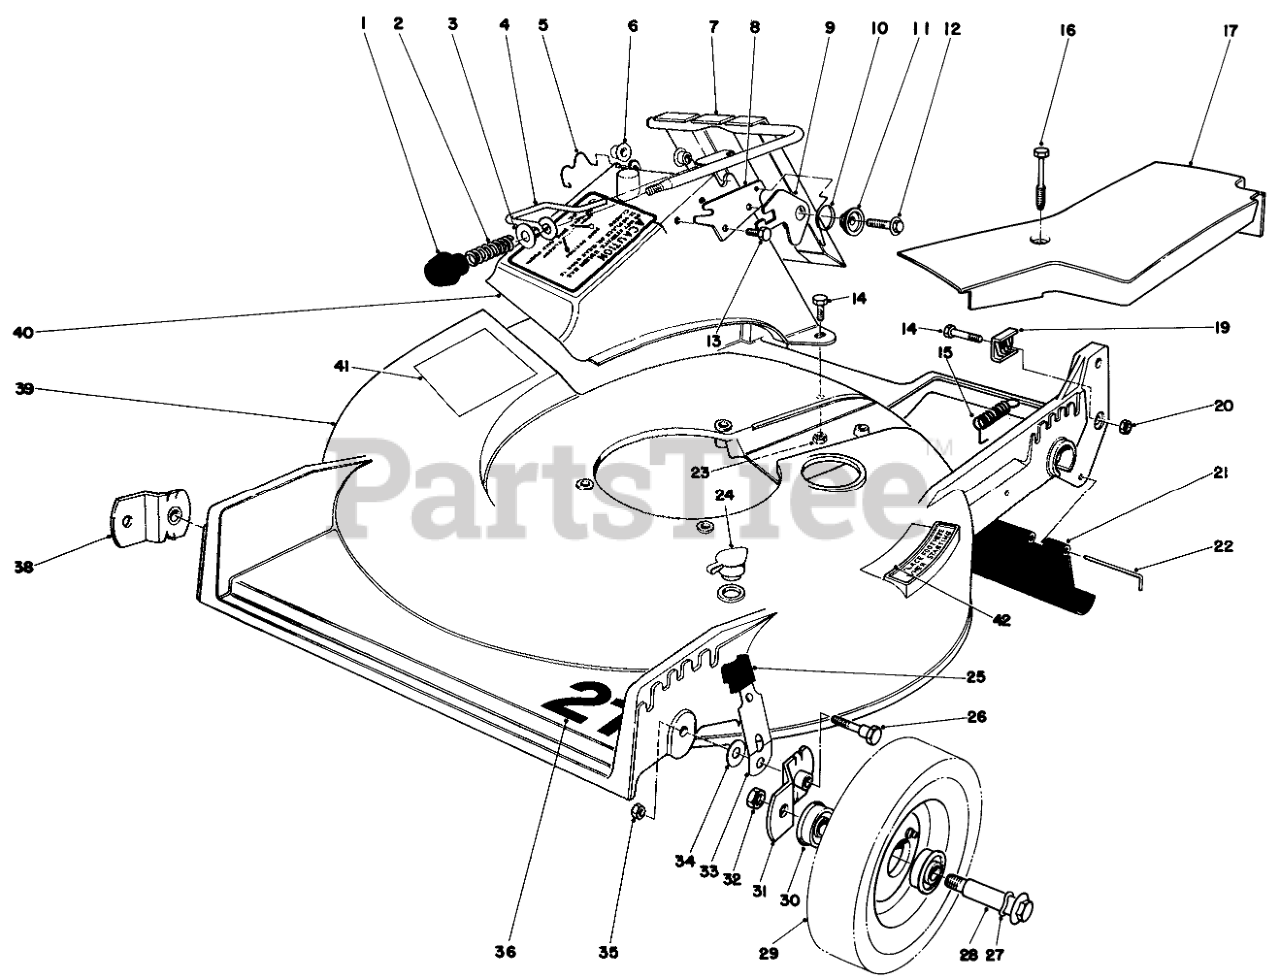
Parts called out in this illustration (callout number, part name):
2	COMPRESSION SPRING
3	WASHER
4	DOOR LATCH
5	Door Retainer
6	BUSHING-NYLON
7	DOOR & HANDLE WA
8	DOOR LATCH PLATE
9	Latch Safety
10	Spring-Torsion
11	Latch Spacer
12	Screw
13	SCREW-HWH
14	SCREW-HH
15	IDLER SPRING
16	SCREW-HHFTF
17	Belt Cover
19	CLAMP-CABLE
20	NUT-JAM
21	SHIELD - TRAILING
22	Rod Shield
23	NUT-LOCK, NI
24	WASHOUT PLUG
25	KNOB-ARM
26	PIVOT SCREW
27	SPRING WASHER
29	Wheel & Tire Assembly (Incl. Ref. #30)
30	BEARING-BALL
31	PIVOT ARM ASM A
32	Nut
33	SPRING ARM ASM (R&S)
34	WASHER-PIVOT
35	Nut
36	Decal 21"
38	PIVOT ARM ASM B
39	Housing
40	DISCHARGE CHUTE B
41	Decal Caution
42	Decal Place Foot Here
